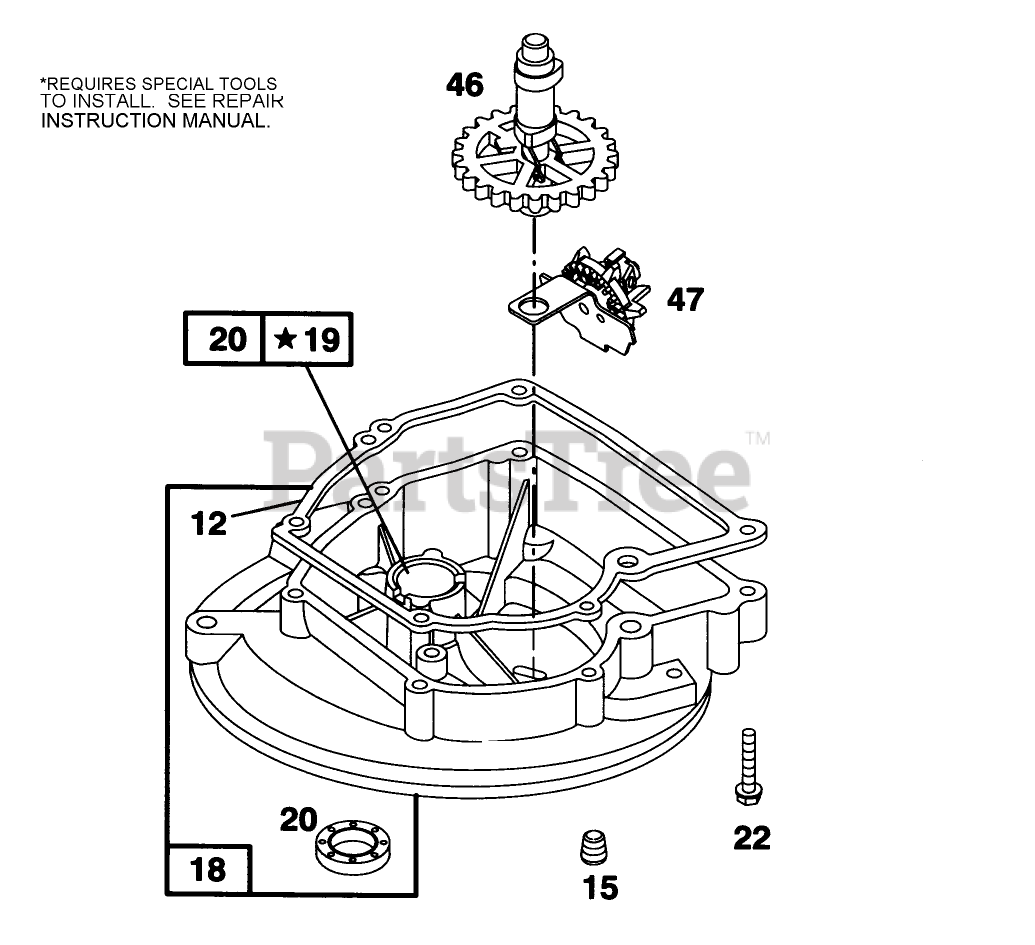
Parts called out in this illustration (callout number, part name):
12	Gasket-Crankcase-.015" thick
15	Plug-Pipe
18	Sump-Oil
19	Bushing-Oil Base
20	Seal-Oil
22	Screw-Mtg. Sem
46	Gear-Cam
47	Oil Slinger Gear and Bracket
